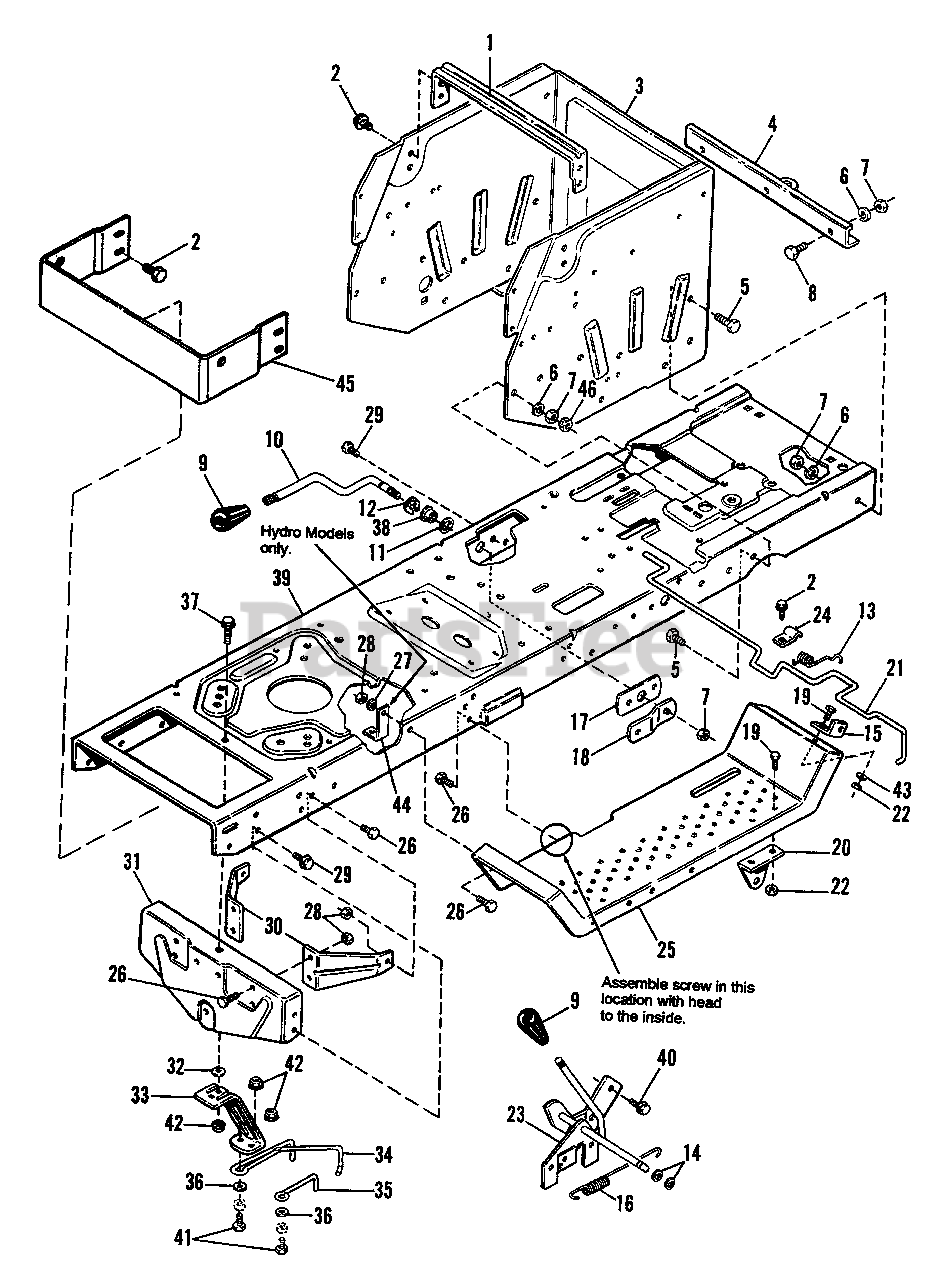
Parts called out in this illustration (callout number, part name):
1	BRACE, Seat
2	SCREW, Taptite, 5/16-18 x 1/2 (Qty. 8 on Hydro Models, Mfg. Nos. 1692156, 1692164, 1692259, 1692283)
3	SUPPORT, Axle Wrapper
4	BAR, Draw
5	CAPSCREW, Hex, 3/8 16 x 1
6	LOCKWASHER, 3/8
7	NUT, Hex, 3/8-16
8	CAPSCREW, Hex, 3/8-16 x 3/4
9	KNOB, Handle
10	HANDLE, Lift
12	KLIPRING, 1/2
13	SPRING, Torsion
14	RING, Retaining
15	BRACKET, Seat Latch
16	SPRING, Extension
17	BAR, Support
18	ARM, Support
19	CAPSCREW, Hex, 1/4-20 x 5/8
20	SUPPORT, Clutch
21	ROD, Latch (Gear Models, Mfg. Nos. 1692160, 1692166; Hydro Models, 1692259, 1692263)
21	ROD, Latch (Hydro Models, Mfg. Nos. 1692156, 1692164)
22	NUT, Hex, 1/4-20
23	HANDLE ASSY., PTO Clutch
26	CAPSCREW, Hex, 5/16-18 x 3/4 (Qty. 6 used on Hydro Models, Mfg. Nos. 1692259, 1692263)
27	LOCKWASHER, 5/16
28	NUT, Hex, Full, 5/16-18 (Qty.18 on Hydro Models, Mfg. Nos. 1692156, 1692164, 1692259, 1692263)
29	SCREW, Taptite 5/16 18 x 3/4 (Qty. 6 used on Hydro Models Mfg. Nos. 1692259, 1692263)
30	BRACE, Axle Support
31	SUPPORT, Axle
32	WASHER, Plain, 11/32-1 x 10 Ga.
36	WASHER, 11/32
37	CAPSCREW, Hex Flange Hd., 5/16-18 x 1-1/4
39	FRAME, (Gear Models, Mfg. 1692160, 1692166, Hydro Mfg. Nos. 1692259, 1692263)
40	SCREW, Taptite, 1/4-20 x 1/2
41	CAPSCREW, Hex 5/16-18 x 7/8
42	LOCKNUT, Hex, Flange Whiz, 5/16-18
43	WASHER
44	BRACKET, Spring (Hydro Model Mfg. Nos. 1692156, 1692164, 1692259, 1692263)
45	SUPPORT, Hood (Gear Models, Mfg. Nos. 1692160, 1692166)
